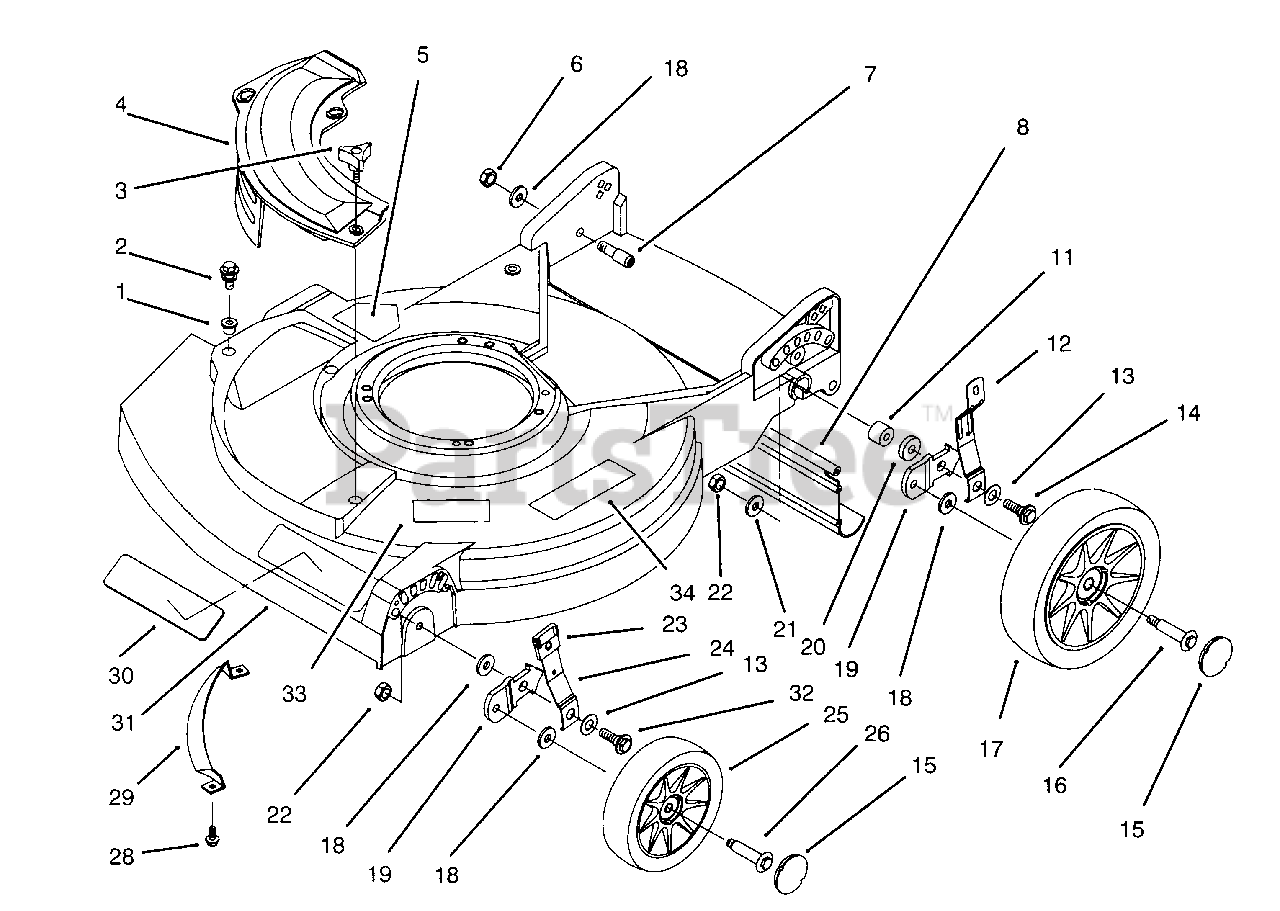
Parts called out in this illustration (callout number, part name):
1	Grommet
2	Screw-Thread From.
3	Knob
4	Cover-Plate, Mulch
5	Decal-Danger
7	Bolt-Shoulder
8	Sheild-Trailing
12	Spring Arm Assembly
13	Washer-Belleville
14	Bolt-Shoulder
16	Bolt-Wheel
17	Wheel Assembly 8"
18	Washer-Wheel Bolt
19	Bracket-H. O. C.
22	Nut-Lock
23	Knob-Spring Arm
24	Spring Arm Assembly
25	Wheel-6"
26	Bolt-Wheel
29	Bar-Toe
30	Applique
31	Housing-21" (Incl. Ref.#5 & 30)
32	Bolt-Shoulder
33	Decal-No Rust
34	Decal-Warning
